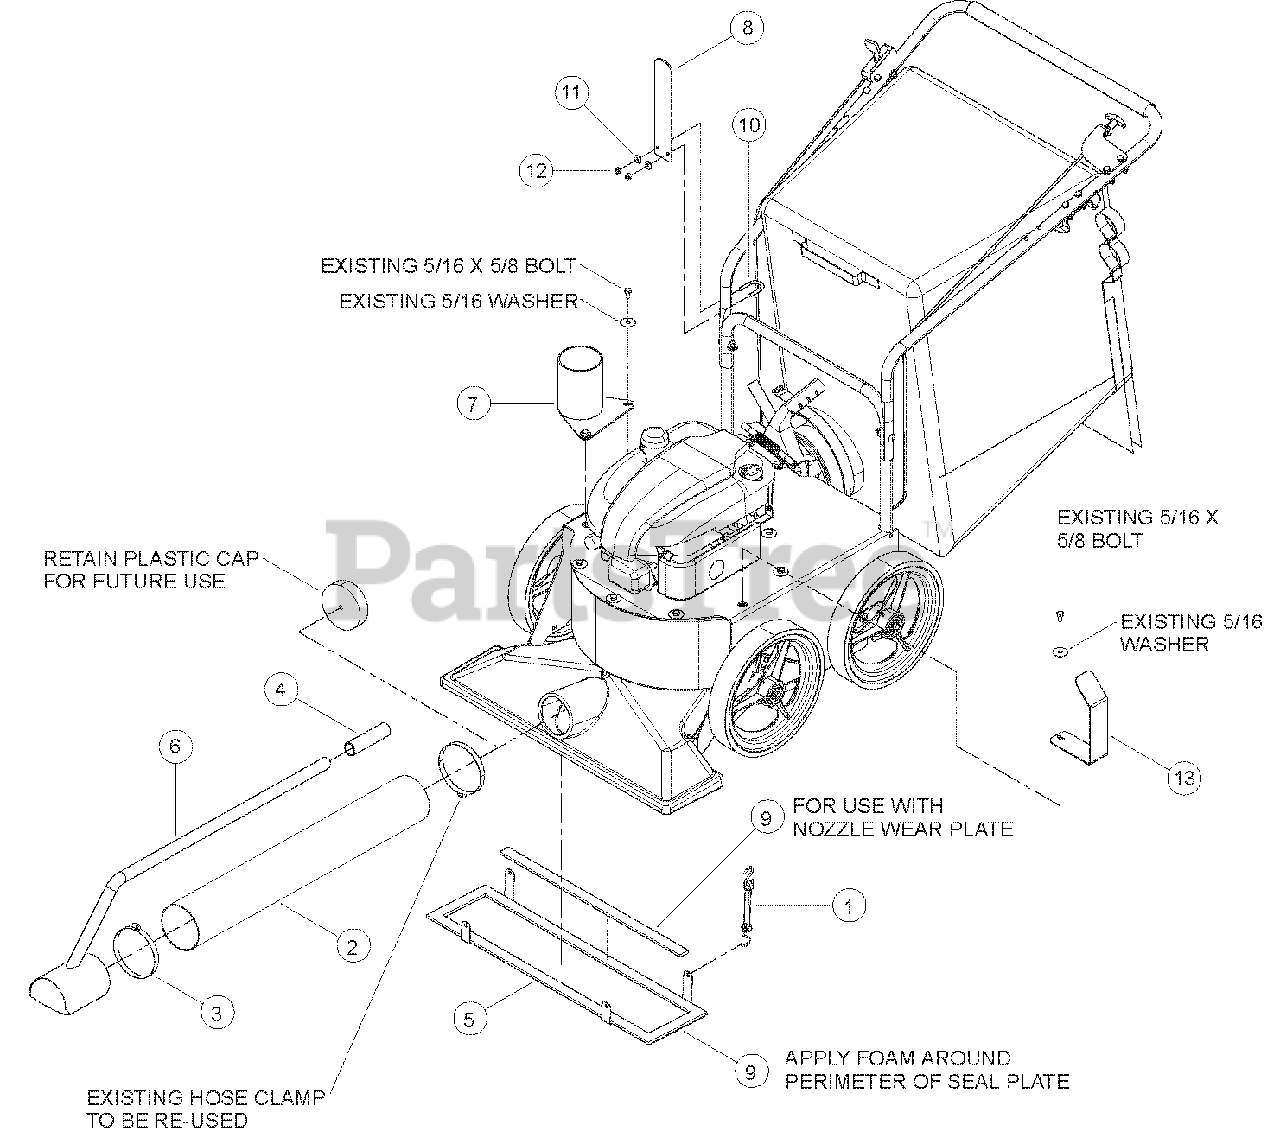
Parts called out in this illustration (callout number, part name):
1	STRAP, 6" TARP
2	HOSE, PVC 4" ID X 10' LG
3	CLAMP, 4" HOSE
4	GRIP - 1" I.D. X 4.63"
5	PLATE, BEAR VAC HOSE KIT SEAL
6	WELDMENT, 4" HOSE NOZZLE
7	WELDMENT, HOSE HOLDER/PLUG
8	STRIP, HOSE HANGER
9	FOAM, PLATE SEAL
10	U-BOLT, 1/4" X 1.0" X 1.75" ZP
11	WASHER, 1/4" FLAT ZP
12	LOCKNUT, 1/4" - 20 NYLON TYPE NE ZP
13	BRACKET, HOSE HOLDER
